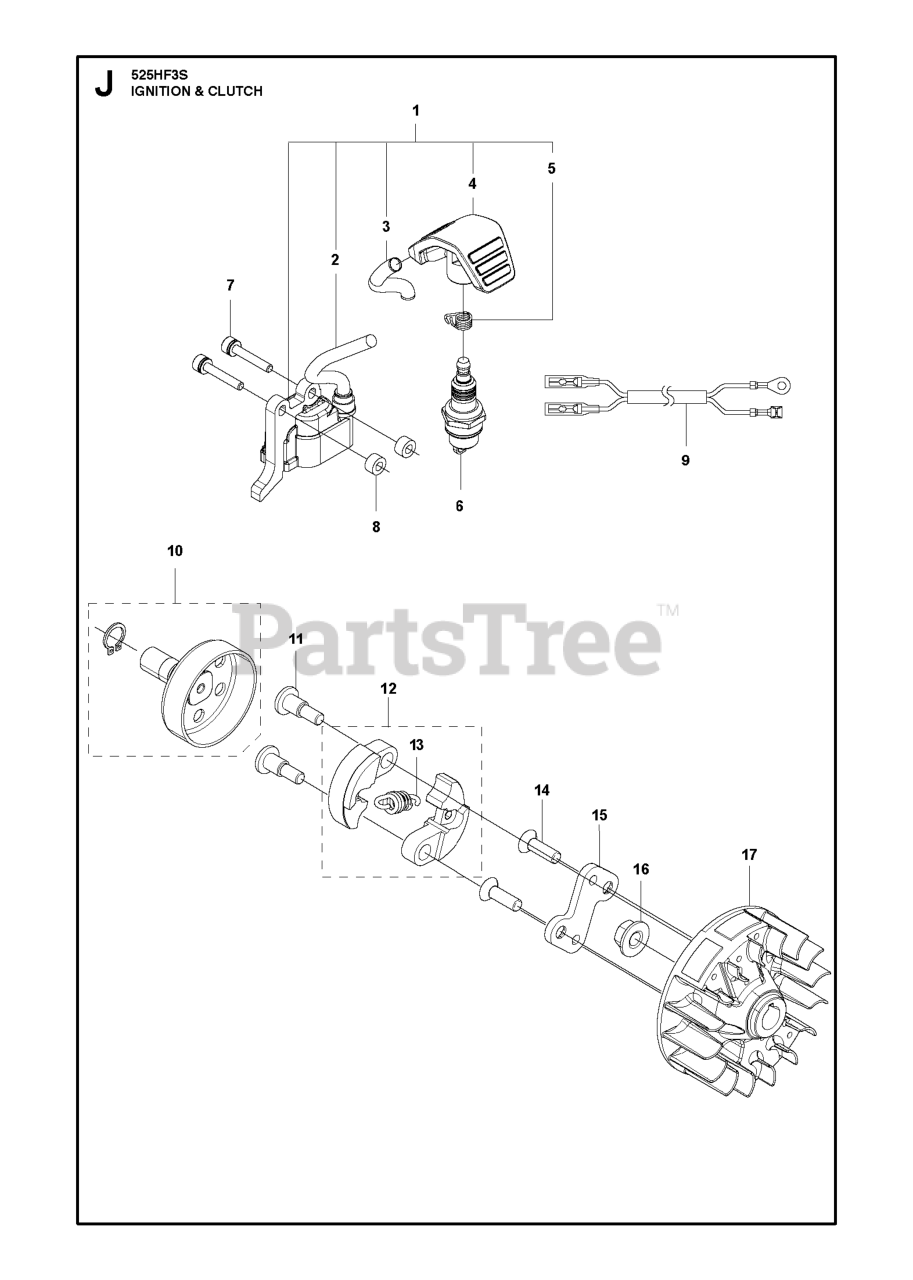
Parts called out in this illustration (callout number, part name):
1	IGNITION COIL ASSY
2	IGNITION CABLE
4	SPARK PLUG CAP
6	SPARK PLUG HQT-2 RESISTOR
7	BOLT M4 X 25
9	SHORT CIRCUIT CABLE
10	KIT CLUTCH DRUM ASSY
11	SCREW CLUTCH
13	CLUTCH SPRING
15	CLUTCH HUB
16	NUT
